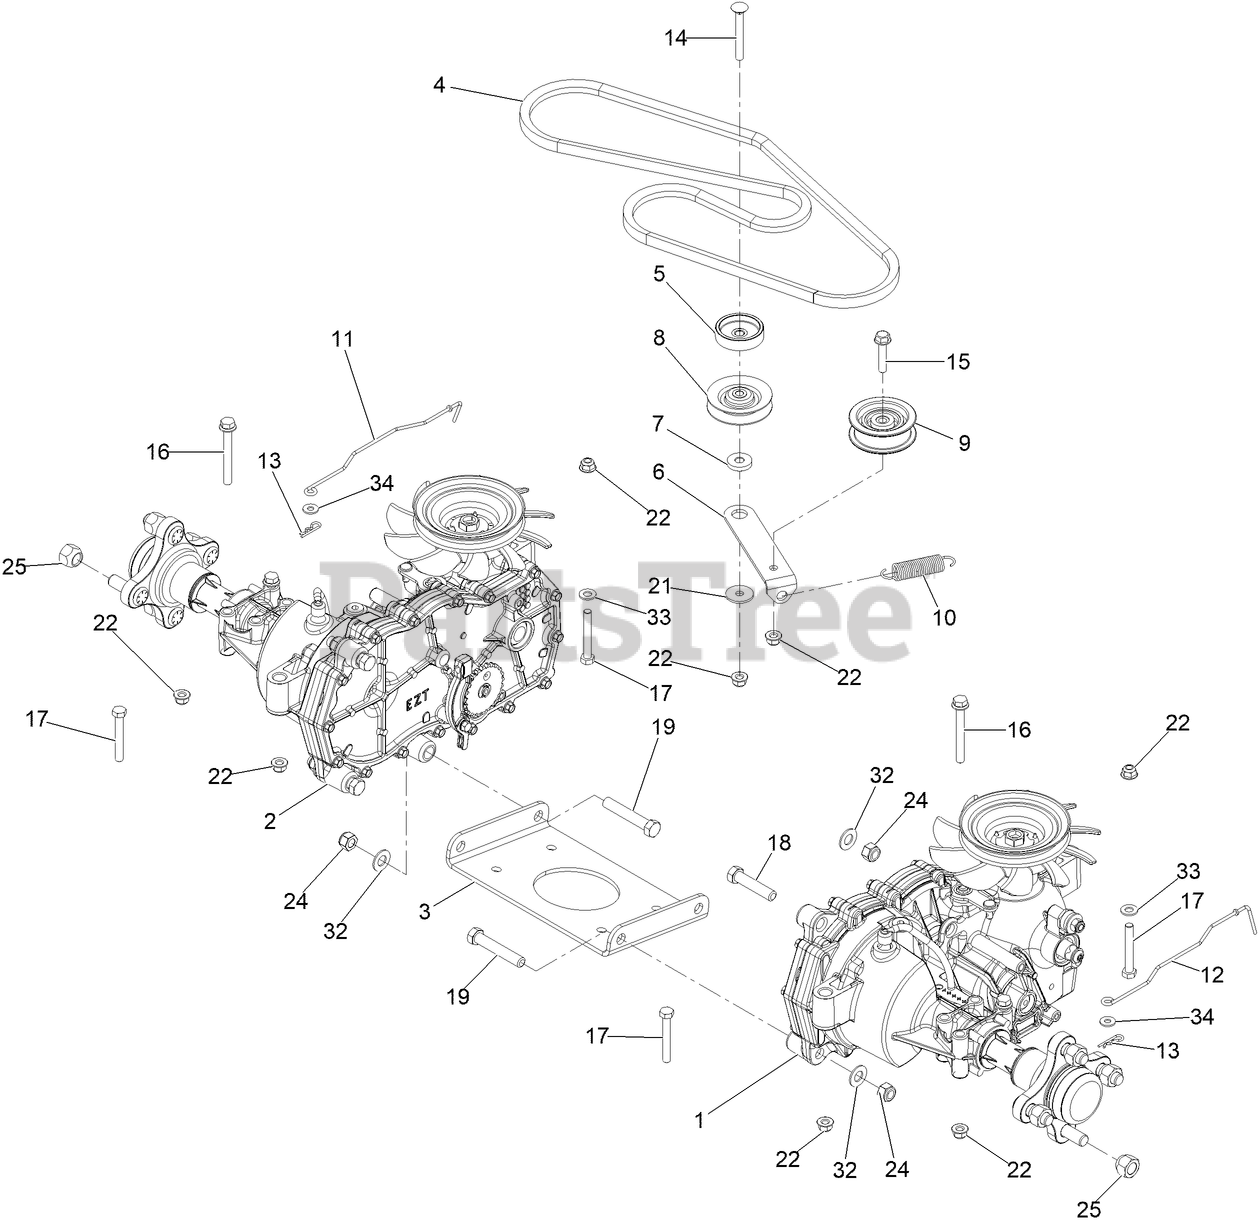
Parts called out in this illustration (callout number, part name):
1	LH HYDRO TRANSAXLE ASM
2	RH HYDRO TRANSAXLE ASM
3	CROSSPLATE-HYDRO
6	Arm-Idler
7	SPACER-ARM, IDLER
9	Pulley-Idler, Flat
10	Spring-Return, Pedal
11	Rod- Bypass,RH
12	Rod- Bypass,LH
14	SCREW-CARR
15	SCREW-HHF
16	SCREW-HHF
17	SCREW-HH
18	SCREW-HH
19	SCREW-HH
21	WASHER-PIVOT
22	NUT-HF, NI
24	NUT-LOCK, NI
25	NUT-LUG
32	WASHER-FLAT
33	WASHER-PLAIN
